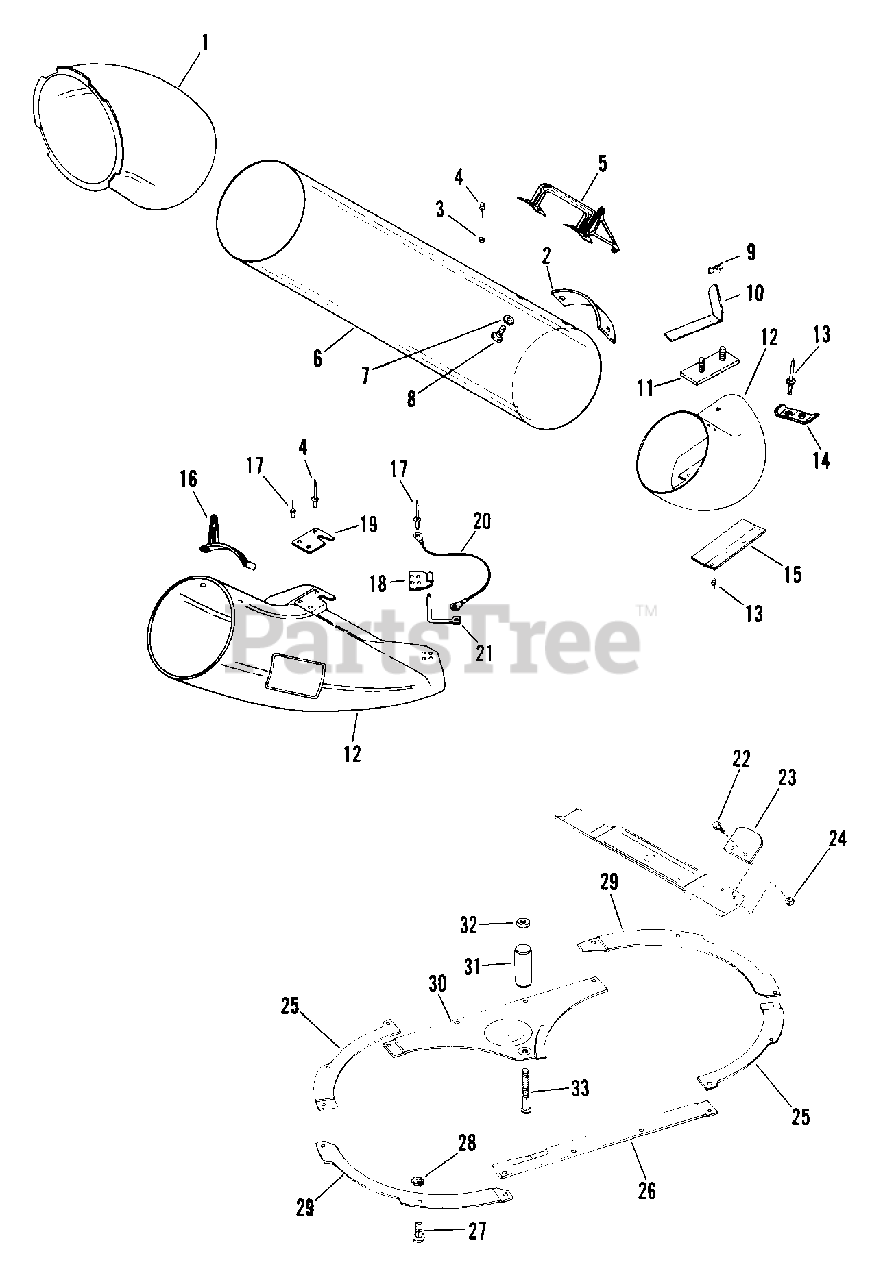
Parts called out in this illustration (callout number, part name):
1	CHUTE DEFLECTOR UNIT
1	BAGGER BOOT
2	BSHG-SLV .334 X .502 X 1.437
2	PLATE
3	SG-TORS .095X.50X 1.0
3	WSHR-FL-STL .194X.492X.047 PL
4	NUT-JAM .50-13 PL
4	RVT-POP.187X.277 DOME ST
5	HANGER HOOK
5	TUBE HANDLE
6	SPACER -FLANGED .325X.498X.318
6	BAGGER TUBE
7	PIN-ROLL .125X.75
7	WSHR-FL-STL.281X.62X.065 PL
8	PIN-COTR .06X.50
8	SCR-TAP 10-16X .75 HWH PL SD
9	BRAKE ROD
10	WSHR-FL-STL .323X.625X.062 PL
11	SG-COMP .057X.47X1.25
12	WSHR-FL-STL .38X.875X.083 PL
12	PAN BOOT
13	BRAKE LEVER
13	RVT-TBLR .187X.375 OH ST PL
14	NUT-LK .312-18 GR A PL
15	WSHR-FL-STL.406X.812X.065PL
16	PIN-HAIR INT .08X.38X1.42 YWZC
16	TUBE RETAINER
17	LINK
17	RVT-POP .187X.402 DOME ST
18	WSHR-LK .44 SP HEAVY
18	BOOT BRACKET
19	BLT-RDHDSQNK .38-16X.75 SHT PL
19	BOOT SUPPORT
20	WSHR-FL-STL .755X1.375X.062 PL
20	LANYARD
21	SPACER .753X1.000X.625
21	PULL PIN
22	SEAL .750X1.690X.153
22	BLT-HEX .31-24X.75 GR8
23	BRG-CUP 1.781X.475
23	SERVICE VANE PACKAGE
24	BRG-CONE .750X.61
24	NUT-LK TOP .312-24 PL GR C
25	SG-COMP .091X.950X2.062
26	SPIN DRIVE ZERK FITTING
27	V-BELT, 4L-RAW EDGE
27	BLT-RDHDSQNK .25-20X.62 PL
28	NUT-JAM SL .75-20 PL
28	NUT-LK-CTR .250-20 PL
29	CAP, GREASE
30	PIN-COTR .12 X 1.25 PL
31	V-BELT, 4L-RAW EDGE
32	SHEAVE 38 IN PAN
32	NUT-LK-CTR .50-13
33	CLEVIS PIN
33	BLT-RDHDSQNK .50-13X5.00 PL
34	PIN-COTR .09X.75 PL
35	WSHR-FL-STL .505X.880X.072 PL
36	PIN-COTR .09X1.0 PL
37	BRAKE BAND
40	SHEAVE
41	KEY-WDRF .188X.75X.313 SAE 9
42	NUT-LK-CTR .375-16 GR A PL
43	BLT-HEX .50-13X1.25 PL GR2
44	BSHG-FLG .500X.625X.500X.750
45	IDLER-FLAT 2.75X.62
46	WSHR-FL-STL .520X.810X.033
47	NUT-LK-CTR .50-13
48	SHOULDER BOLT .50 X 1.00
50	SG-TENS .112X.89X5.28 WLD 56
51	PIN-COTR .12X1.0 PL
52	ADJUSTMENT LINK
53	WSHR-FL-STL .531X1.062X.095 PL
54	ADJUSTMENT PLATE
55	38" MOWER PAN W/DECALS
55	38" MOWER ASSEMBLY
56	WSHR-FL-STL .755X1.250X.125
57	BEARING SLINGER
58	BRG-BALL .750X1.781X.61
59	SPINDLE HOUSING
60	BLT-HEX .38-16X.75 PL GR2
61	SPACER .753X1.000X1.140
62	RETAINER HUB
63	BLADE TRAY
64	MOWER BLADE
65	NUT-JAM .75-10 PL
66	WSHR-LK .750X.188 MED PL
67	BLT-HEX .38-16X1.00 PL
68	CLEVIS PIN
69	NUT .50-13 PL
